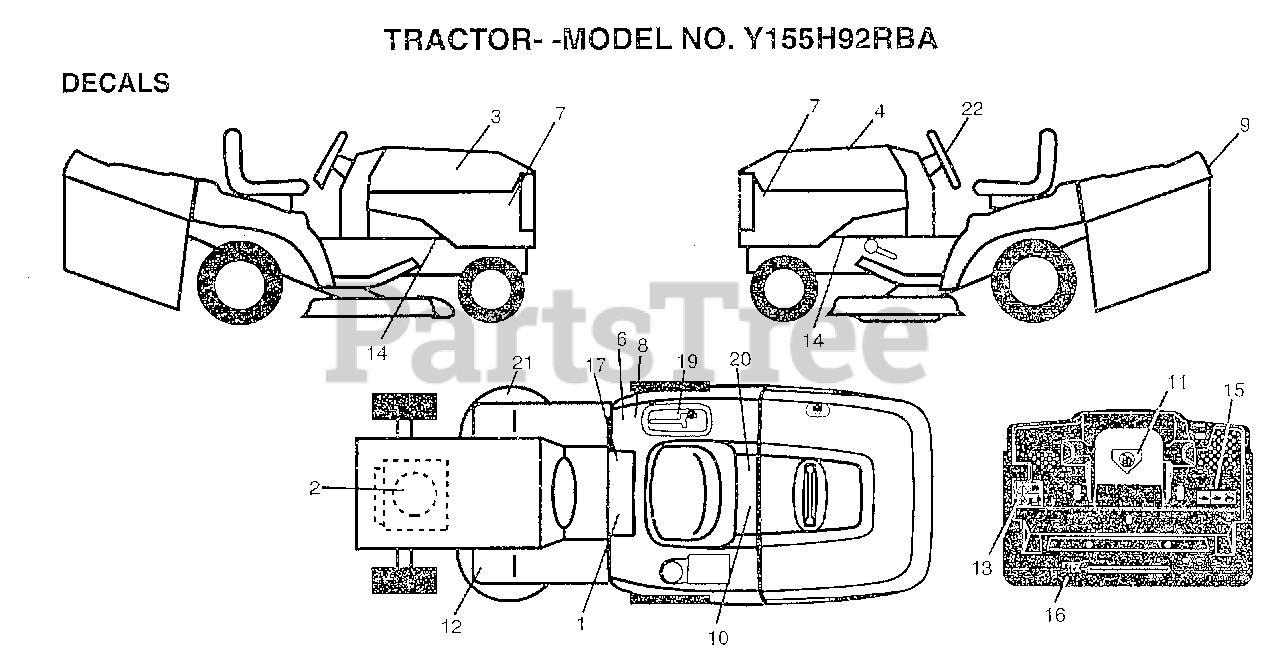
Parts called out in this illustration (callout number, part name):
1	DECAL.READ.O.MANU
3	DECAL.HD.RH.
4	DECAL.HD.LH.
7	DECAL.SD.PNL.HD/DECK SIZE
8	DECAL.EURO.ST.CE.
10	DECAL.BATRY.3-3908
11	DECAL.DANGER.CUTF
12	DECAL-BRAKE/CLUTC
13	DECAL.WARNING.BACKPLATE.CRD
14	"DECAL CHASSIS,HOT"
15	DECAL, OPER BAG
16	DECAL.DRAWBAR.LDL
17	DECAL BRAK PARK
19	DECAL.BYPASS.FENDER.CRD.
20	DECAL.BYPASS.FENDER.CRD.LT.YT
21	DECAL.DECK.HEX.BELT
22	DECAL.INS.STRG.WH
